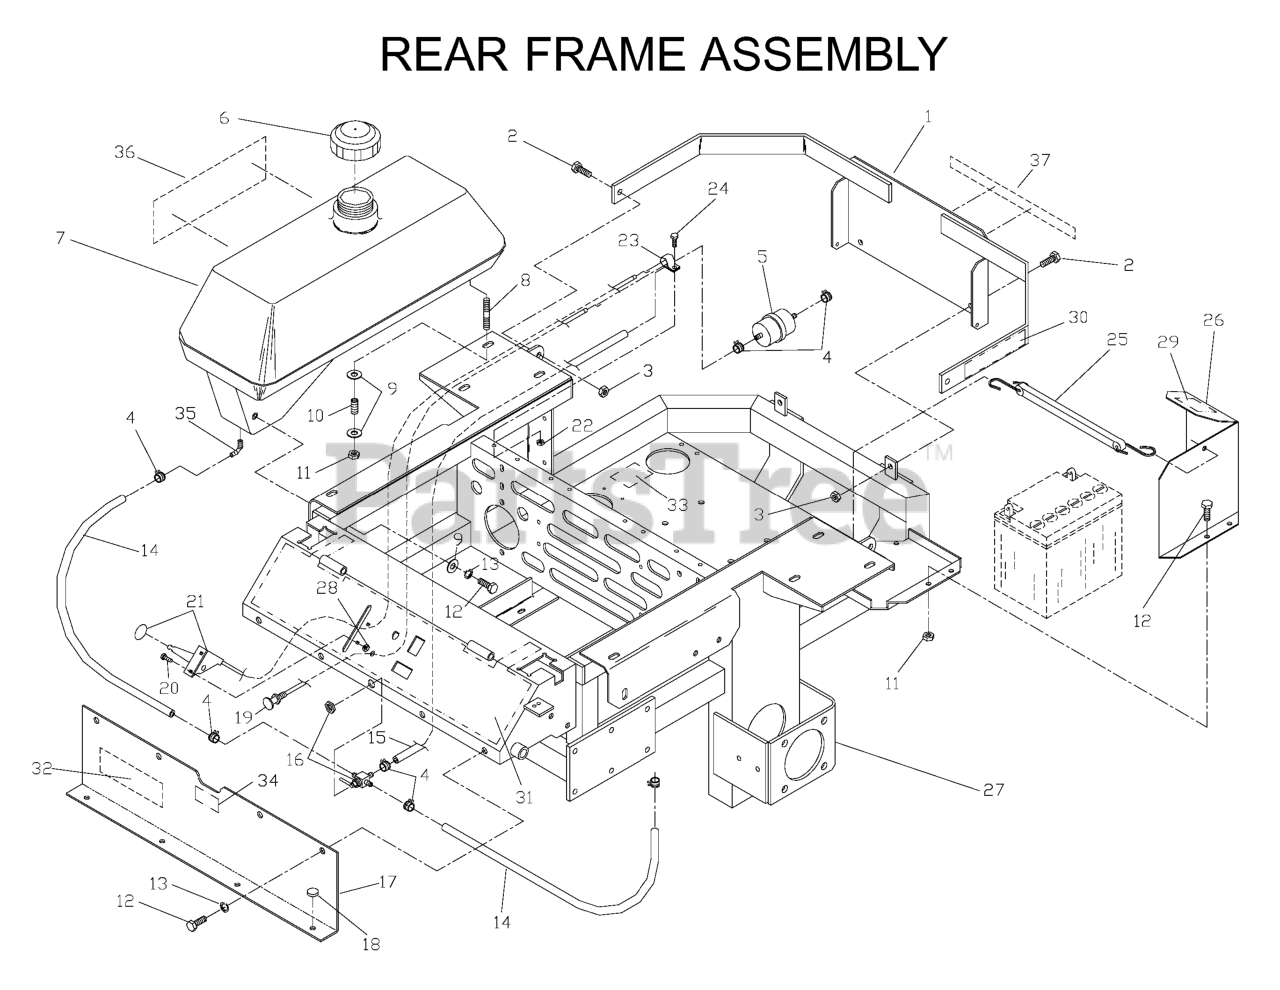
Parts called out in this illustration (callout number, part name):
1	REAR ENG GRD W/DECALS
2	HCS 3/8-16X1.GRD.5.ZD
3	NUT 3/8C CENTERBLOCK
4	HOSE CLAMP
5	FUEL FILTER
8	STUD, 5/16C
9	FLAT WASHER 5/16 SAE
11	NUT 5/16C CENTERLOCK
12	HCS 5/16C X 3/4
13	WASHER.LOCK.HVY.HLCL.SPR.5/16
14	FUEL LINE 21.5" TANK
15	FUEL LINE, ENGINE
16	FUEL VALVE
17	KICK PLATE
18	GROMMET, BUMPER
19	CHOKE CONTROL, COMPLETE
20	HCS #10-24 X 1/2
21	THROTTLE CONTROL W/BALL KNOB
22	NUT 1/4C CENTERLOCK
24	HCS 1/4C X 3/4 HCS
25	BATTERY STRAP
26	BATTERY GUARD W/DECALS
27	REAR FRAME W/DECAL
28	NUT 10-24 NYLOC
29	DECAL, PROP. 65
30	DECAL, BATTERY
31	CONSOLE DECAL
32	DECAL, NASCAR
33	DECAL, EXHAUST
34	DECAL, FUEL VALVE
35	HOSE BARB 90 DEGREE
36	DECAL ZTH5223
37	DECAL, HUSQVARNA LOGO 9.25"
539104801	DECAL ZTH5225
539104802	DECAL, ZTH6125
